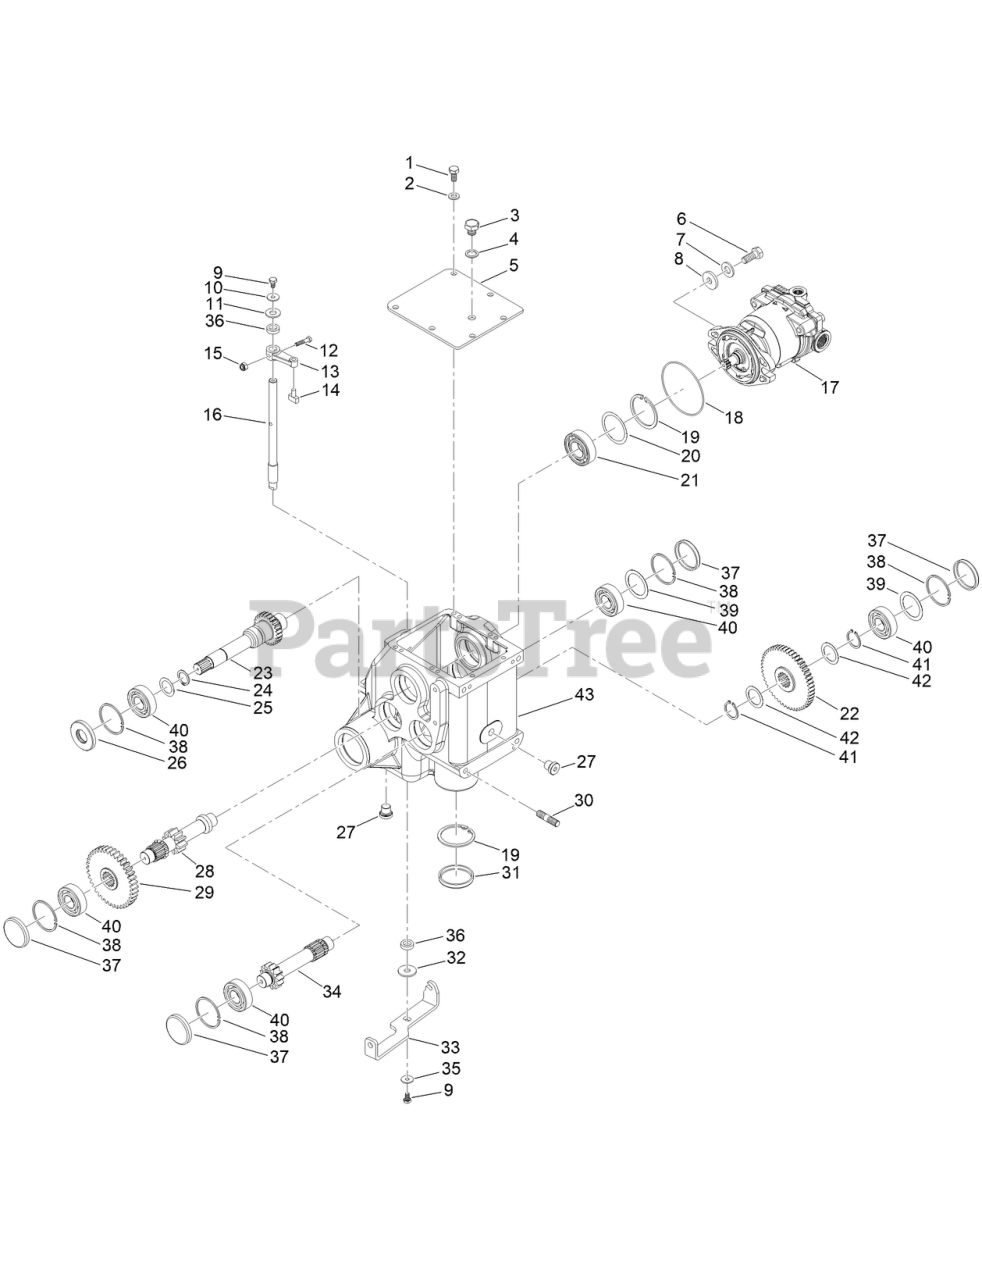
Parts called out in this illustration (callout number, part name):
2	WASHER
3	PLUG-HH
4	WASHER
5	COVER, TRANSMISSION GEARBOX
7	WASHER
8	WASHER
10	WASHER
11	WASHER
12	SCREW-HH CAP
13	LEVER, DIFFERENTIAL LOCK
14	PAD, DIFFERENTIAL LOCK
16	SHAFT, DIFFERENTIAL LOCK
17	MOTOR, TRANSMISSION
18	O-RING
19	RING-RETAINING, INT
20	SPACER
21	BEARING
22	SPUR GEAR, SECONDARY SHAFT
23	SHAFT, PRIMARY TRANSMISSION GEARBOX
24	RING-RETAINING, INT
25	SPACER
26	OIL SEAL
27	PLUG, GEARBOX
28	SHAFT, TERTIARY TRANSMISSION GEARBOX
29	SPUR GEAR, TERTIARY SHAFT
32	WASHER
33	BRACKET, DIFFERENTIAL LOCK
34	SHAFT, SECONDARY TRANSMISSION GEARBOX
35	WASHER
36	OIL SEAL,
37	PLUG, RCA
38	RETAINER, HUB
40	BEARING, DIA 20 X 47 X 14
41	RETAINER, SHAFT
43	GEARBOX
